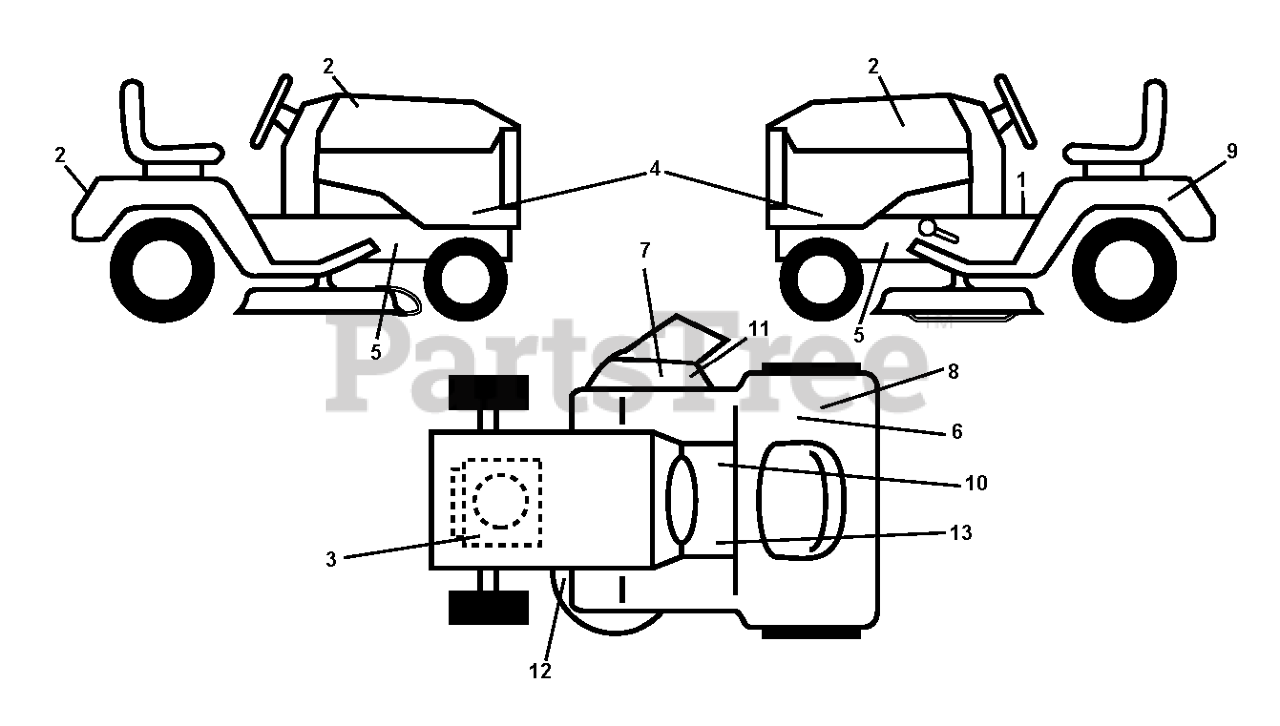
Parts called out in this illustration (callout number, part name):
1	LABEL
2	DECAL.HOOD.LOGO.ORANGE.HUSQVAR
3	DECAL
6	DECAL 80 DBA
7	DECAL.INTERNATIONL.CUTFINGER
8	DECAL
9	DECAL BTRY SYMBOLS
10	DECAL PARK BRAKE
11	DECAL, DEFLECT WARNING
12	DECAL.V-BELT.SCHEMATIC.36/38/9
13	DECAL
